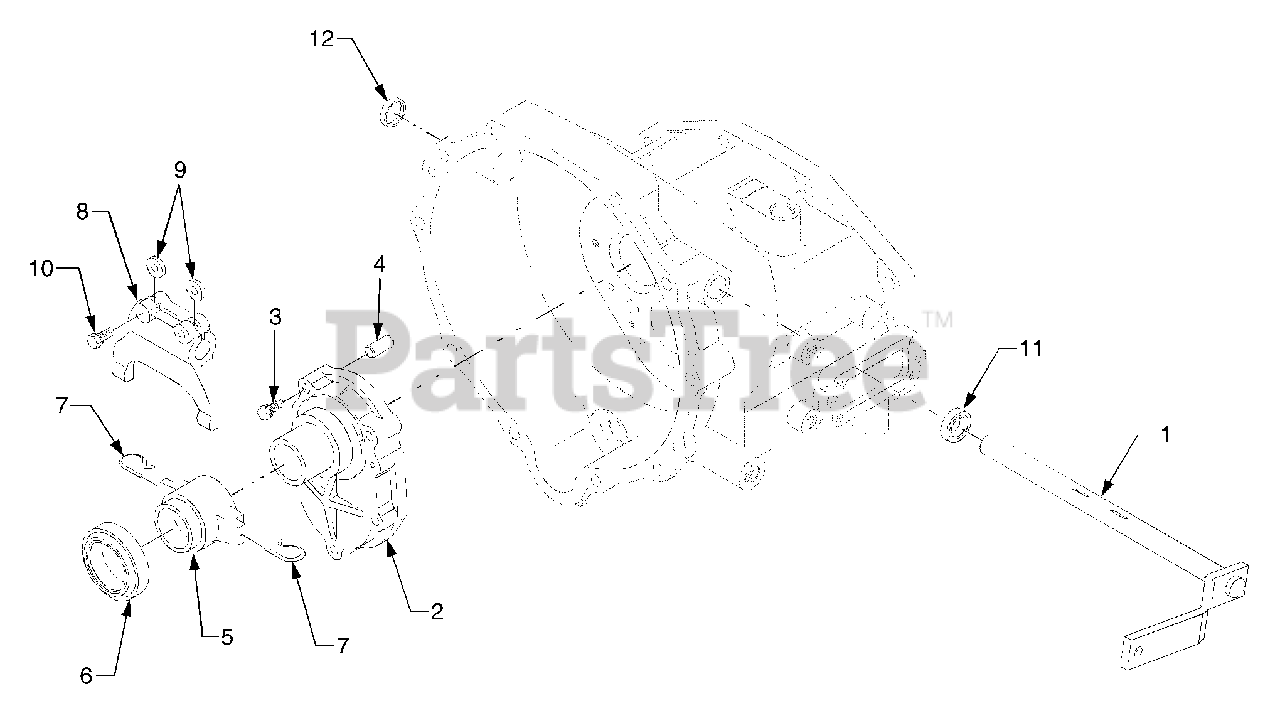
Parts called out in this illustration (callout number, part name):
1	Lever, Main Clutch
2	Case, Propeller Shaft
4	Pin, Straight
5	Hub, Clutch Release
6	Bearing, Release
8	Fork, Clutch Release
